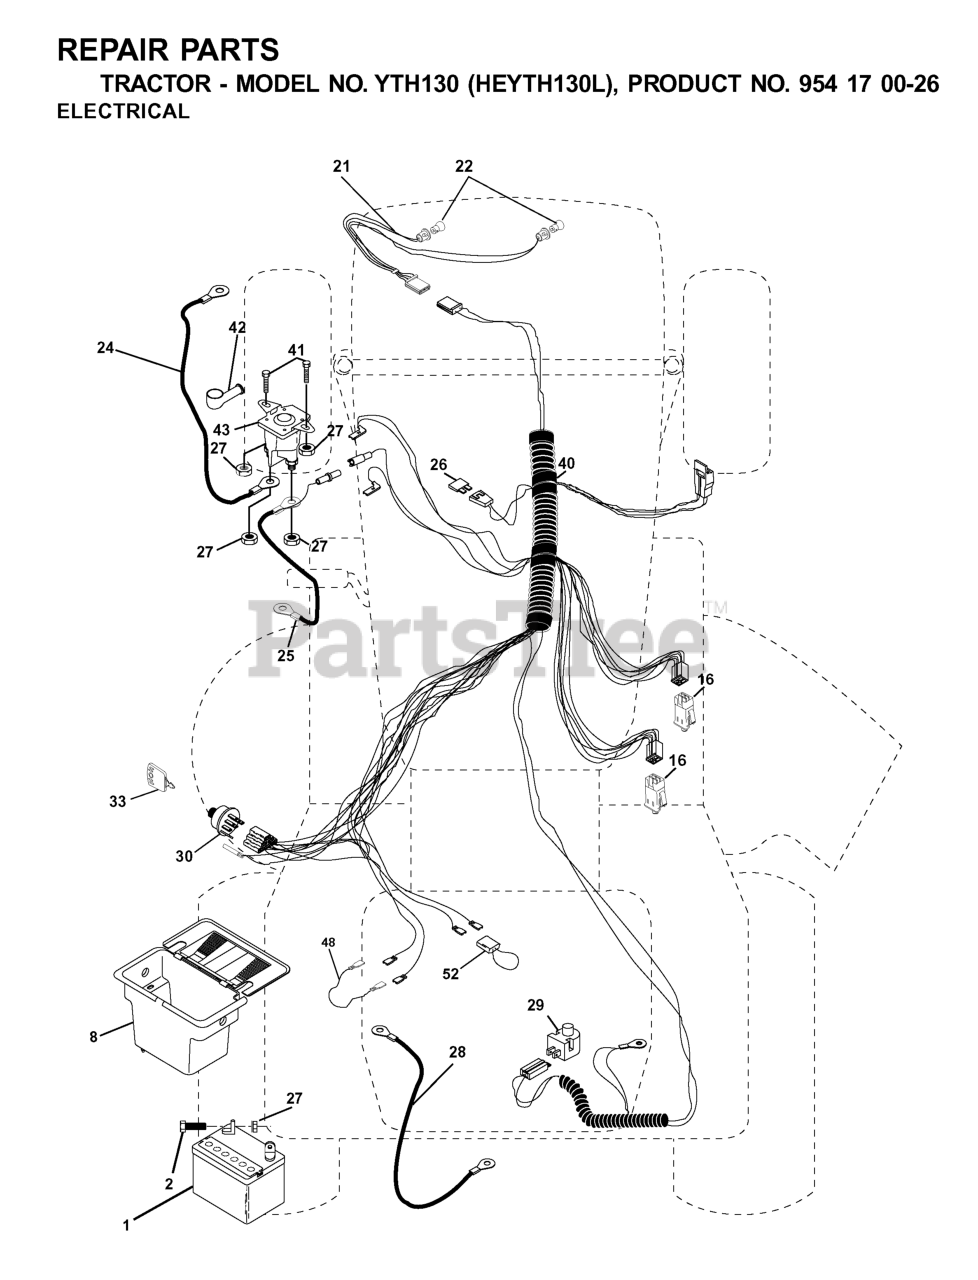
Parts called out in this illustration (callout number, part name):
1	BATTERY 12 VOLT 25 AMP
2	BOLT.HEX.1/4.X.3/4.DICHROMATE
8	CASE BATTERY MECH HINGE
16	SWITCH INTERLOCK
24	BATTERY CABLE
25	CABLE BATTERY
26	FUSE 20AMP
27	NUT
29	RP.SWITCH.PLUNGER.NC.GRAY
30	IGNITION SWITCH
33	KEY MLD GEN DELTA
40	CABLE, IGN. HARNESS
41	BOLT
42	TERMINAL COVER
43	REPL BY 532 1461-54
48	ADAPTER.AMMETER
52	WIRE PROTECTION LOOP
